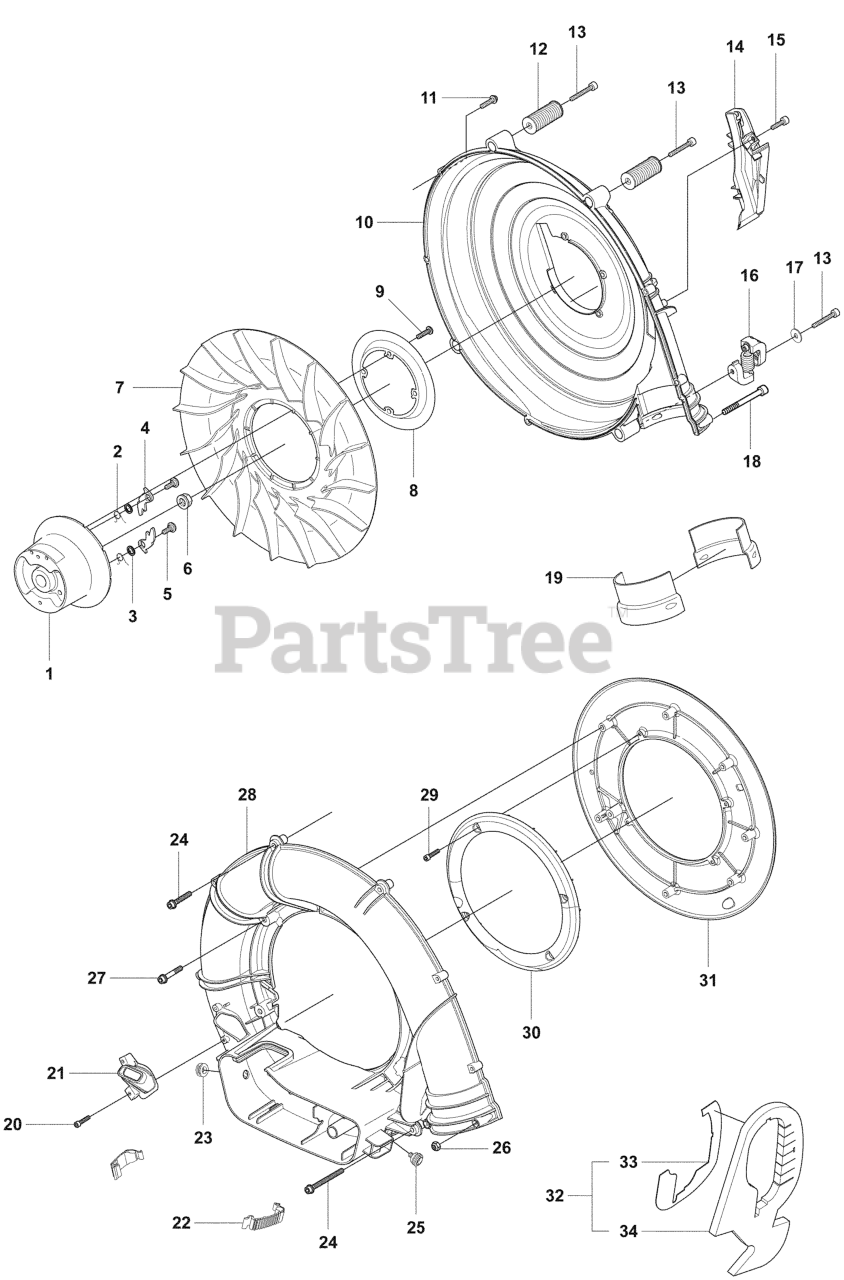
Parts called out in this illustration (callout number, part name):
5	SCREW M5X14
6	NUT W/ WASHER
14	AIR CONDUCTOR
22	BUCKLE ORANGE
33	TAPE DOUBLE-STICK
